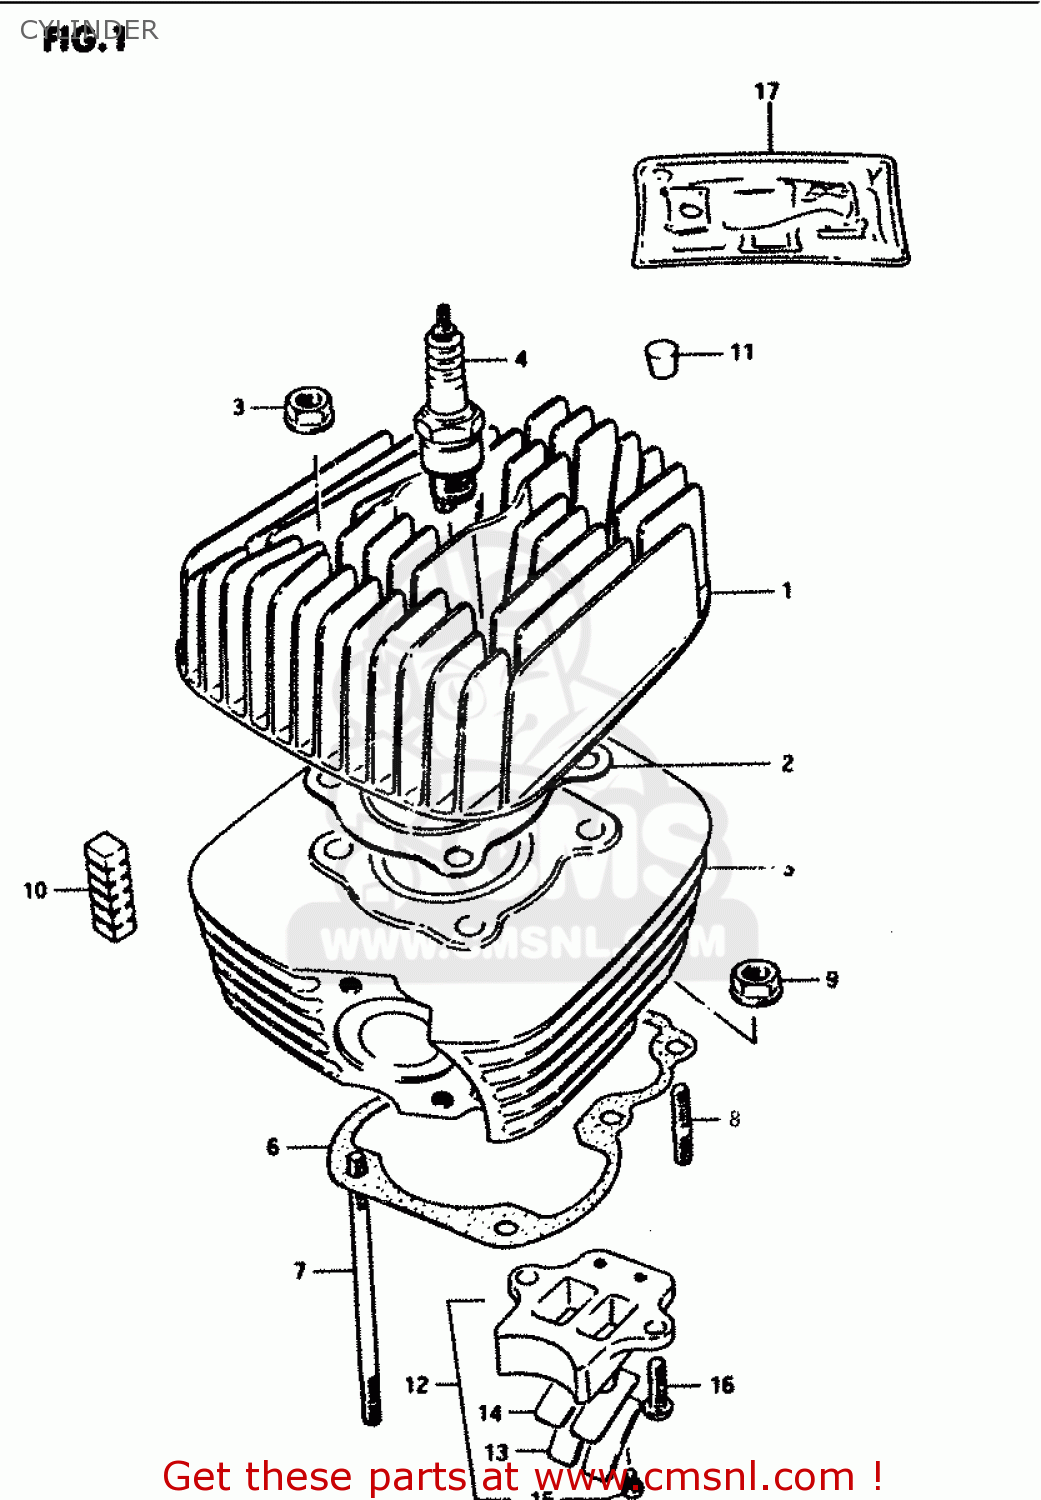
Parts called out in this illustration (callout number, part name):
1	HEAD,CYLINDER
2	GASKET,CYLINDER HEAD
3	NUT
4	PLUG,SPARK(BPR6HS)
5	CYLINDER
6	GASKET,CYLINDER (NAS)
7	BOLT,STUD
8	STUD 6X16
9	NUT
10	PAD,CYLINDER
11	PAD,CYLINDER HEAD
12	VALVE ASSY,REED
13	STOPPER,REED VALVE
14	VALVE,REED
15	SCREW
16	SCREW
17	GASKET SET
